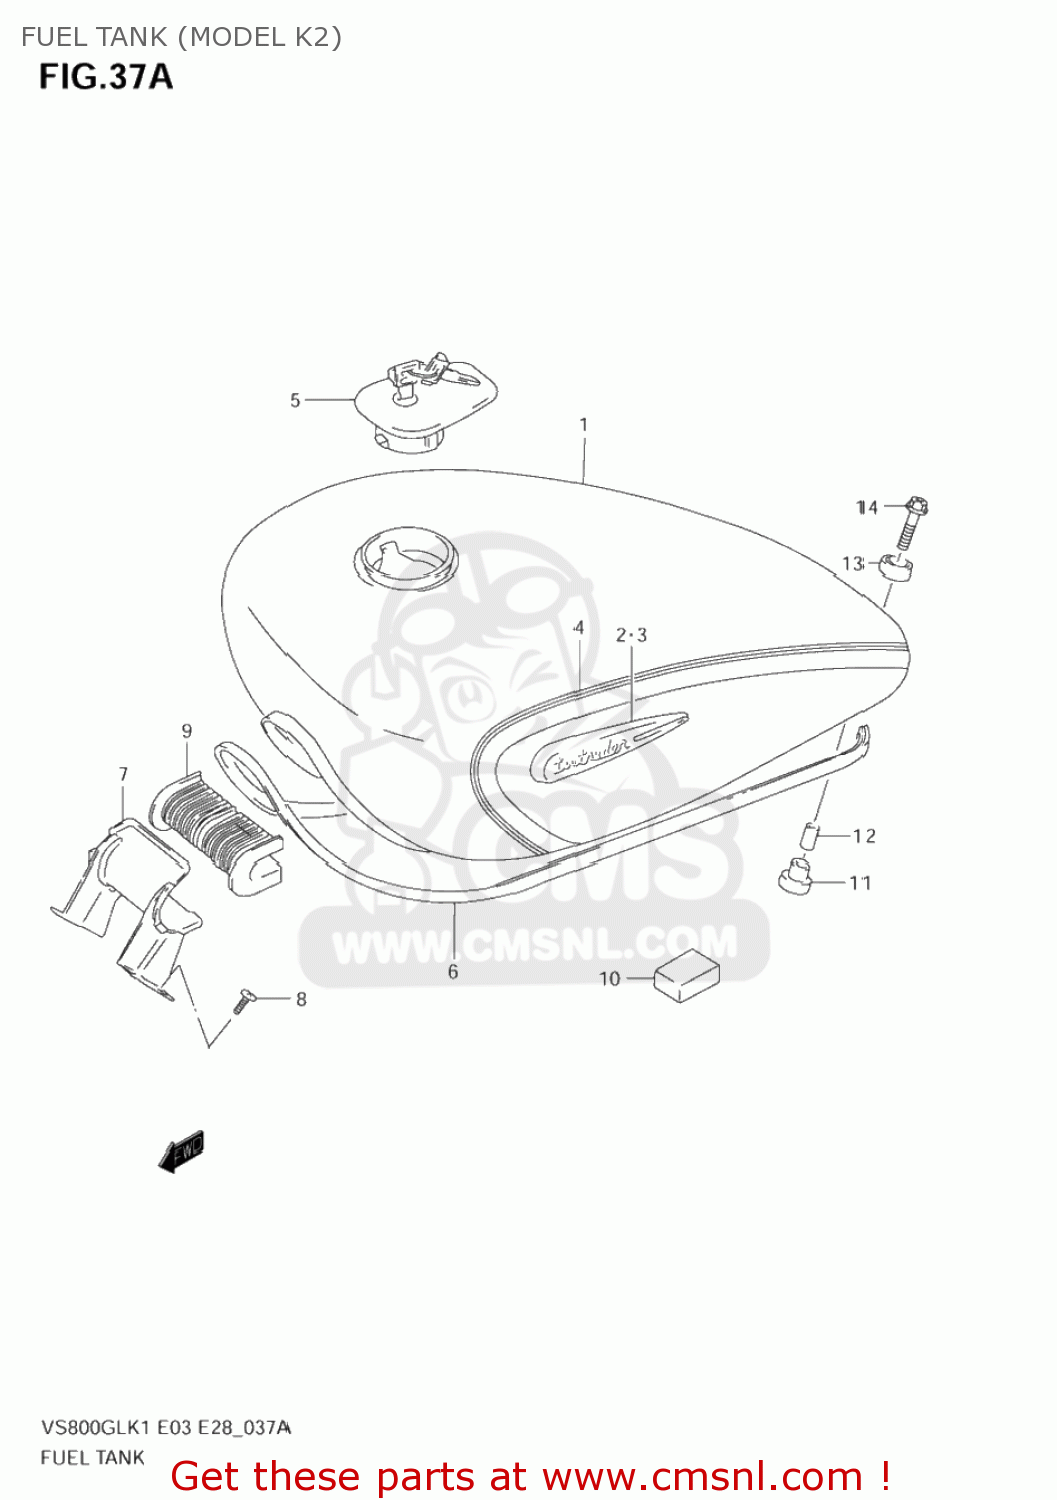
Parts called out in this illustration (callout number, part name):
1	TANK ASSY,FUEL(BLACK)
2	EMBLEM,FUEL TANK,R
3	EMBLEM,FUEL TANK,L
4	TAPE SET,FUEL TANK
5	CAP SET,FUEL TANK
6	MOLDING
7	BRACKET,FUEL TANK FR
8	SCREW
9	CUSHION,FUEL TANK FR
10	CUSHION
11	CUSHION
12	SPACER(6.5X9X21.5)
13	CUSHION
14	SCREW(6X35)
